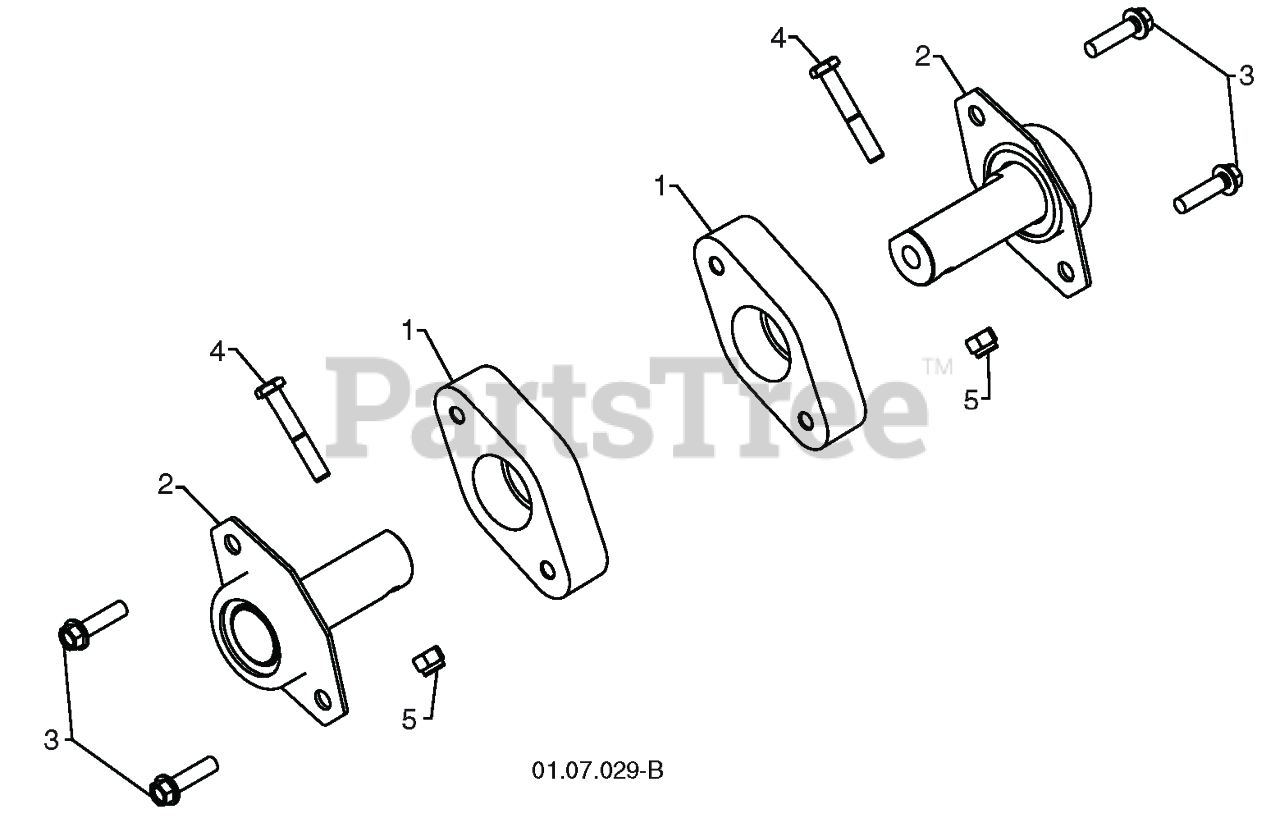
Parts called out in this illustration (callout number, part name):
1	BAIL.ARM.ASSY:STRAIGHT OM
2	HANDLE.UP.DST.SS/VS.FG/RG.NHGY
3	HANDLE.LOWER.DOME.BT.GREY
4	GUIDE.ROPE.BLK.ZINC.CHROM
5	T-KNOB.NEW ROPE GUIDE
6	BOLT, HANDLE 5/16-18X1.75
7	TIE GUIDE
8	BOLT.FIN.HEX.5/16-18X3/4
9	BRACKET.ASM.HOUSING.EZ.MUL
10	DOOR.MULCH.21".REAR.PUSH.GRAY
11	CONTROL.ZONE.ASM
13	BRACKET.UPSTOP.RT
14	KNOB.HANDLE.PLASTIC.STAR.BLACK
18	SCREW 1/4X20
19	AXLE ARM ASSY FRONT LH
20	AXLE ARM ASSY FRONT RH
21	SKIRT.REAR.21.PUSH
22	SELECTOR SPRING, FRONT
23	DOOR.REAR.21.DOMED.498
25	BRACKET ASM.HAND.HW.21.LT.498
26	BRACKET.ASM.HAND.HW.21.RT.498
29	WHEEL ADJ BRACKET FRONT
30	SPACER.HEIGHT.ADJUSTER
31	DEFLECTOR.CLIPPING.21.GREY
32	SPRING.SEL.22.ECON.HI-WHL.RATO
33	SELECTOR KNOB
34	ARM ASM.AXLE.BZP
35	NUT.FLANGE.HEX.5/16X18.BLACK
36	SHOULDER BOLT 5/16-18
37	WHEEL & TIRES ASSY, FRONT
39	NUT.HEX.FLANGE.3/8-16.LOCKNUT
40	FRAME.BAG.21.REAR.DOMED.PUSH
41	SCREW.1/4-20X21/4.HEX.
42	SPRING.LH.22.REAR.DOOR.EZ.EMPT
43	SPRING.RH.22.REAR.DOOR.EZ.
45	BOLT 3/8-16X1-1/8
46	DANGER DECAL
47	NUT.LOCK.5/16-18
49	WHEEL.11X1.75.H3SPK.RAD3.BB1
50	GBAG.2323029ER.HU.VENT.GRY.SIL
51	ROD.HINGE.COMBI-C
52	HOUSING.21.M/C.DOME.ORANGE
53	RP_SCREW.HEX.HEAD.3/8-24X1.1/8
54	LOCKWASHER
55	WASHER,HARDEN
56	BLADE.21.PUSH/RWGD/FWGD
57	ADAPTER.BLADE.W/KEY.25MM.CE
58	TORSION SPRING
61	NUT.HEX.FLANGE.3/8-16.LO(3 2)
62	LOCKNUT.NYLOC.1/4-20
65	WASHER.FLAT.1/2
66	O-RING..070X.487.NEOPRENE
73	WASHER.CURVED.CYLINDRICAL
74	WASHER.ENGINE.BZP
76	BAFFLE.REAR.PLASTIC.21.RD.ECON
77	SCREW.HX.13X.750
83	BAFFLE.FRONT.21.DOME.US
84	BOLT.5/16HEX.WHS.HD
87	PLUG.PLASTIC.7/8".14-20.GAUGE
88	BOLT.CARRIAGE.LN.5/16-18X.5/8
89	LOCKNUT-FLANGE 5/16-18
